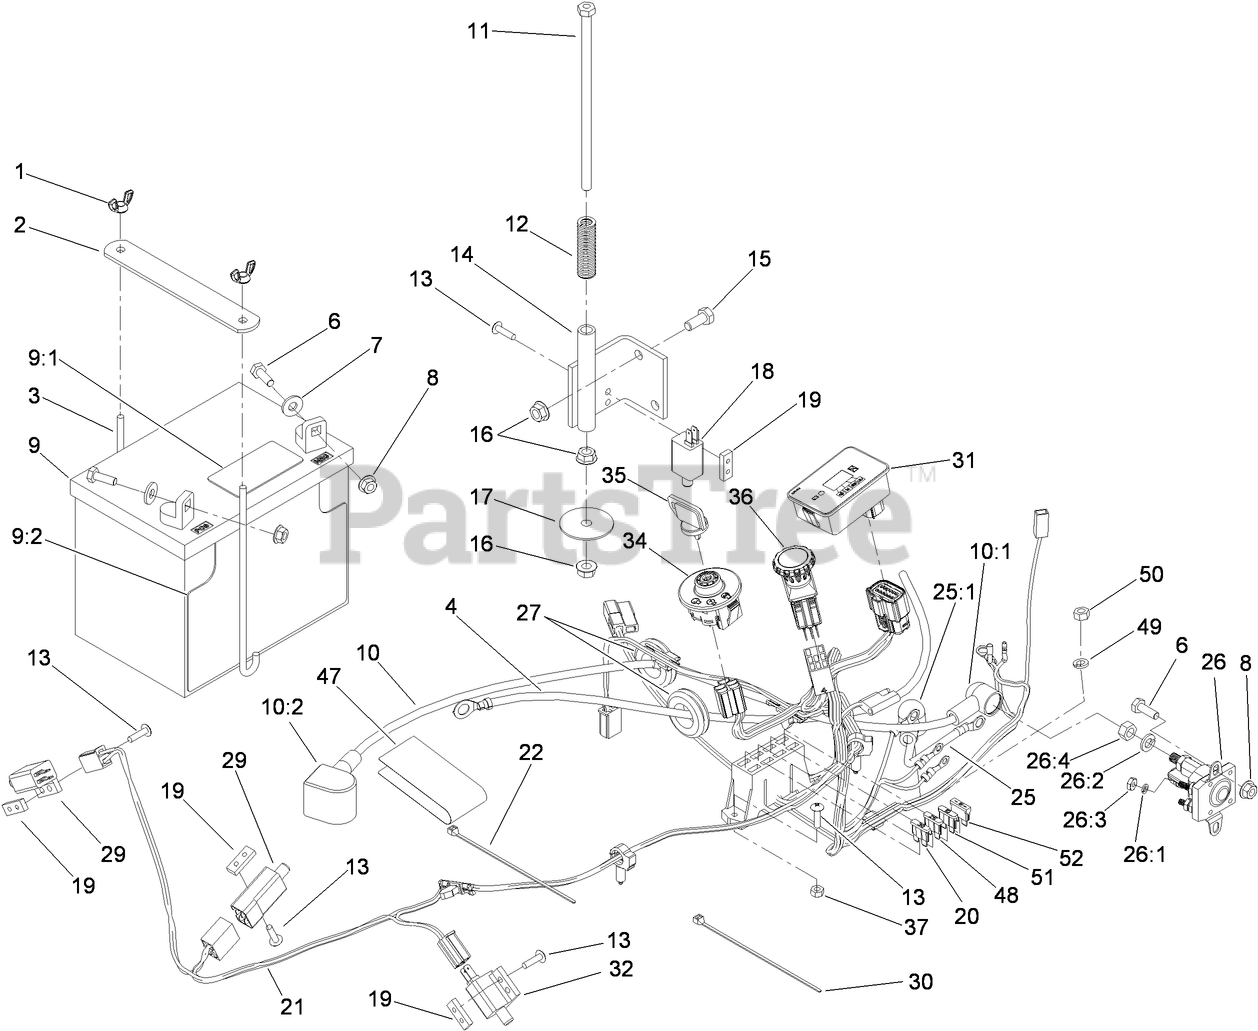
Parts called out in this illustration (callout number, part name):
1	WINGNUT
2	STRAP-HOLDDOWN, BATTERY
3	BOLT-HOLDDOWN
4	CABLE-GROUND, NEGATIVE
6	SCREW-HH
7	WASHER-FLAT
8	NUT-HF
9	BATTERY
9:1	Decal-Battery
9:2	Decal-Battery
10	POSITIVE BATTERY CABLE ASM
10:1	INSULATOR-SOLENOID
10:2	INSULATOR-BATTERY
11	SCREW-HH
12	SPRING-SWITCH, SEAT
13	SCREW-HEAD, TRUSS
14	BRACKET-SWITCH, SEAT
15	SCREW-HH
16	NUT-HF
17	WASHER
18	SWITCH-CLOSED, NORMALLY
19	PLATE-TAPPED
20	FUSE-BLADE, 30 AMP
21	HARNESS-ELECTRICAL
22	TIE-CABLE
25	POSITIVE STARTER CABLE ASM
25:1	INSULATOR-SOLENOID
26	SWITCH-SOLENOID
26:1	WASHER-LOCK
26:2	WASHER-LOCK
26:3	NUT-HEX
26:4	NUT-JAM
27	GROMMET
29	SWITCH-OPEN, NORMALLY
30	TIE-PLASTIC
31	HOUR METER ASM
32	SWITCH
34	SWITCH-IGNITION
35	KEY-IGNITION
36	SWITCH-PTO, 10 AMP
37	NUT-LOCK, NI
47	DECAL-INSTRUCTIONS, CHARGING
48	FUSE-BLADE, 25 AMP
49	WASHER-LOCK
50	NUT-HEX
51	FUSE-BLADE, 10 AMP
52	FUSE-BLADE, 15 AMP
